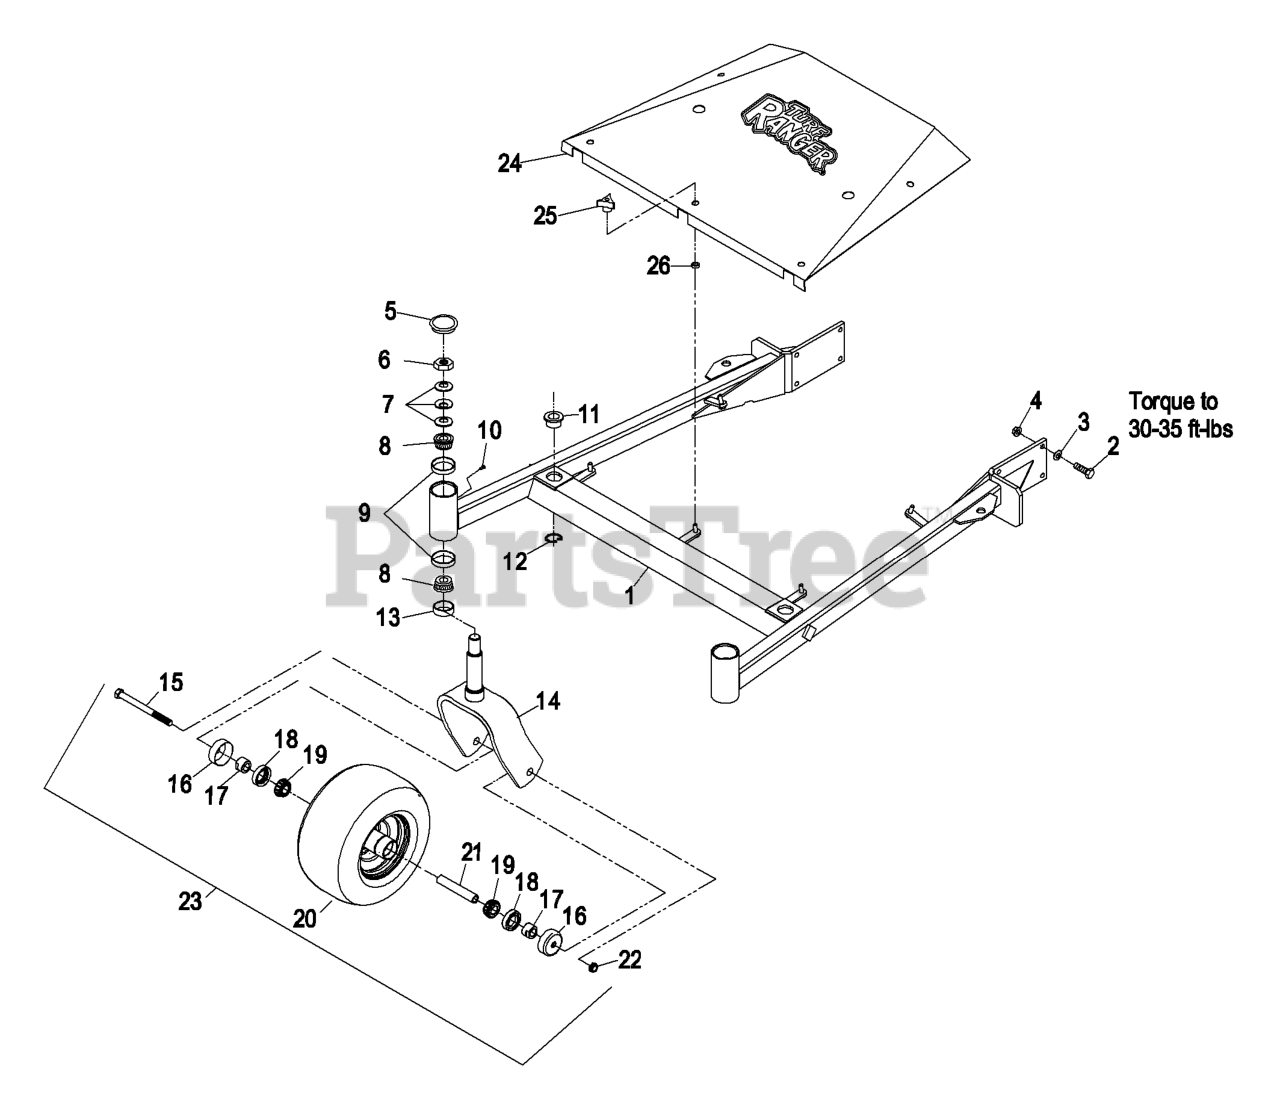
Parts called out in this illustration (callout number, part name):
1	ASM,524 FMD DK SUPPORT,SE
2	SCREW-HH
3	WASHER-BELLEVILLE
4	NUT-HHF, WHIZ
5	CAP-GREASE
6	NUT-LOCK, NI
7	WASHER-BELLVILLE
8	Cone-Bearing Tapered Roller
9	CUP-BEARING
11	BUSHING-DECK
12	RING-RETAINING
13	SEAL-GREASE
14	WLD, CASTER FORK
15	SCREW-HH
16	GUARD-SEAL
17	SPACER-NUT
18	SEAL-CASTER
19	BEARING-CONE, TAPERED ROLLER
22	NUT-HEX
23	WHEEL AND TIRE ASM
24	KIT,SHIELD TR W/ DECALS F
25	KNOB-3 PRONG
